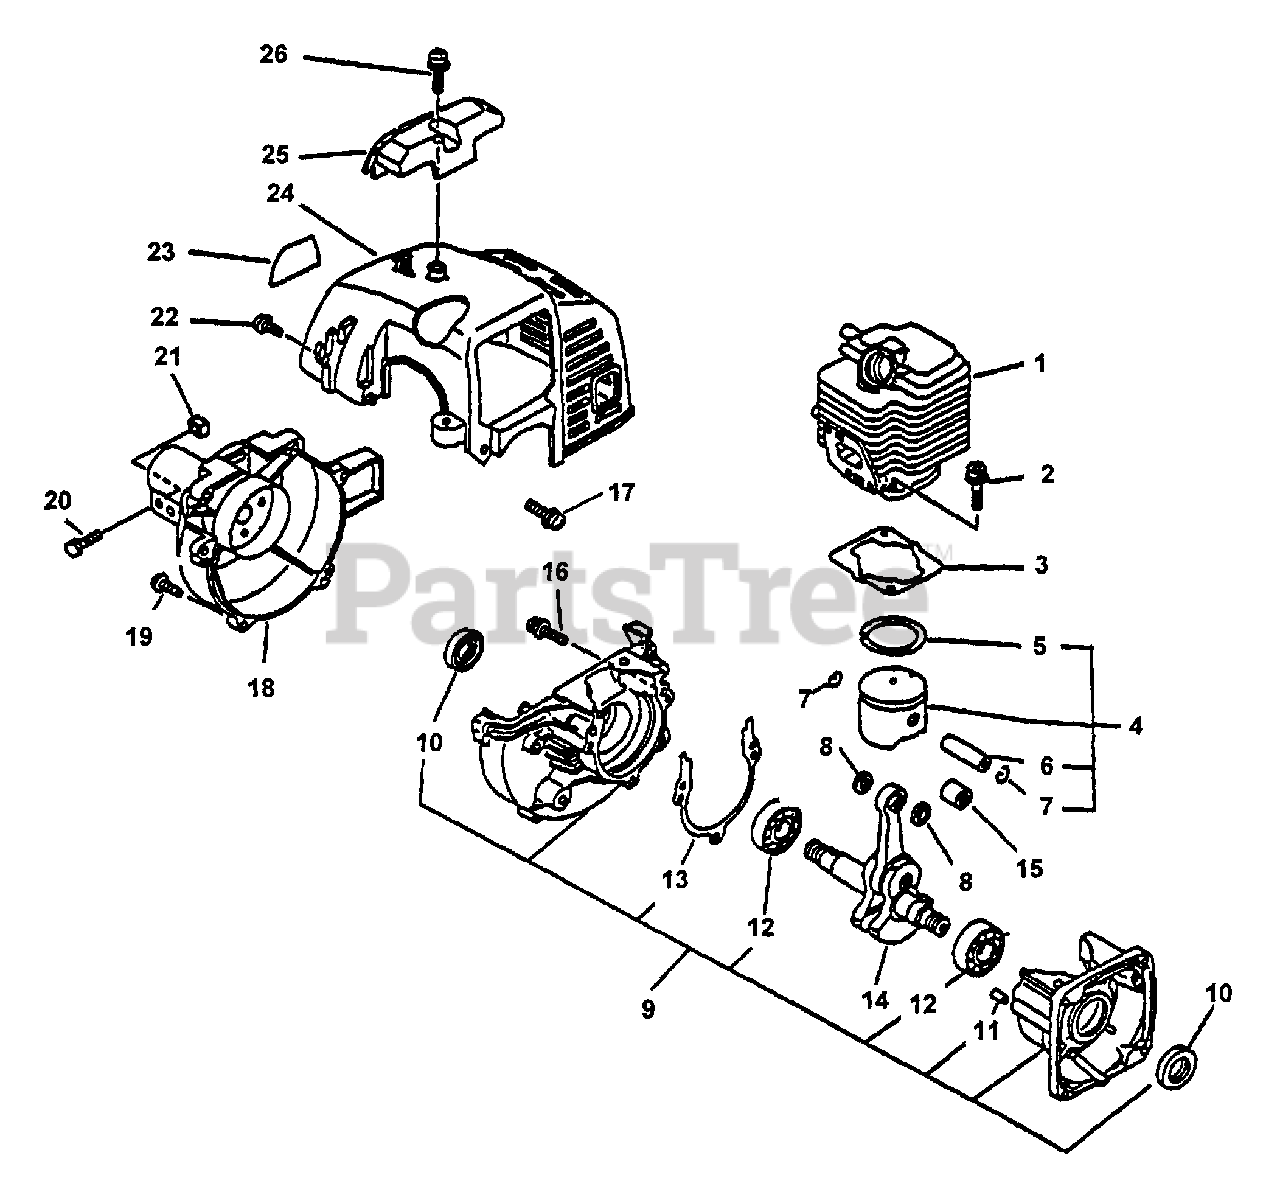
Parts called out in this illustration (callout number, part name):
1	CYLINDER
2	BOLT 5×22
3	GASKET, CYLINDER
4	PISTON KIT
5	RING, PISTON
6	PIN, PISTON 8
7	RING, SNAP
8	WASHER, THRUST
9	CRANKCASE KIT
10	SEAL, OIL 12
11	PIN, LOCATING 4
12	BEARING, BALL - 6201 C3
13	GASKET, CRANKCASE
14	CRANKSHAFT ASSY
15	BEARING, NEEDLE
16	BOLT 5×28
17	SCREW 4×12
18	FAN CASE ASSY
19	SCREW - 4×18
20	BOLT 5×28
21	NUT M5
22	BOLT 4×16
23	LABEL, PE-2000
24	COVER, ENGINE - GRAY
25	GUARD, TOP - GRAY
26	SCREW 5×16
